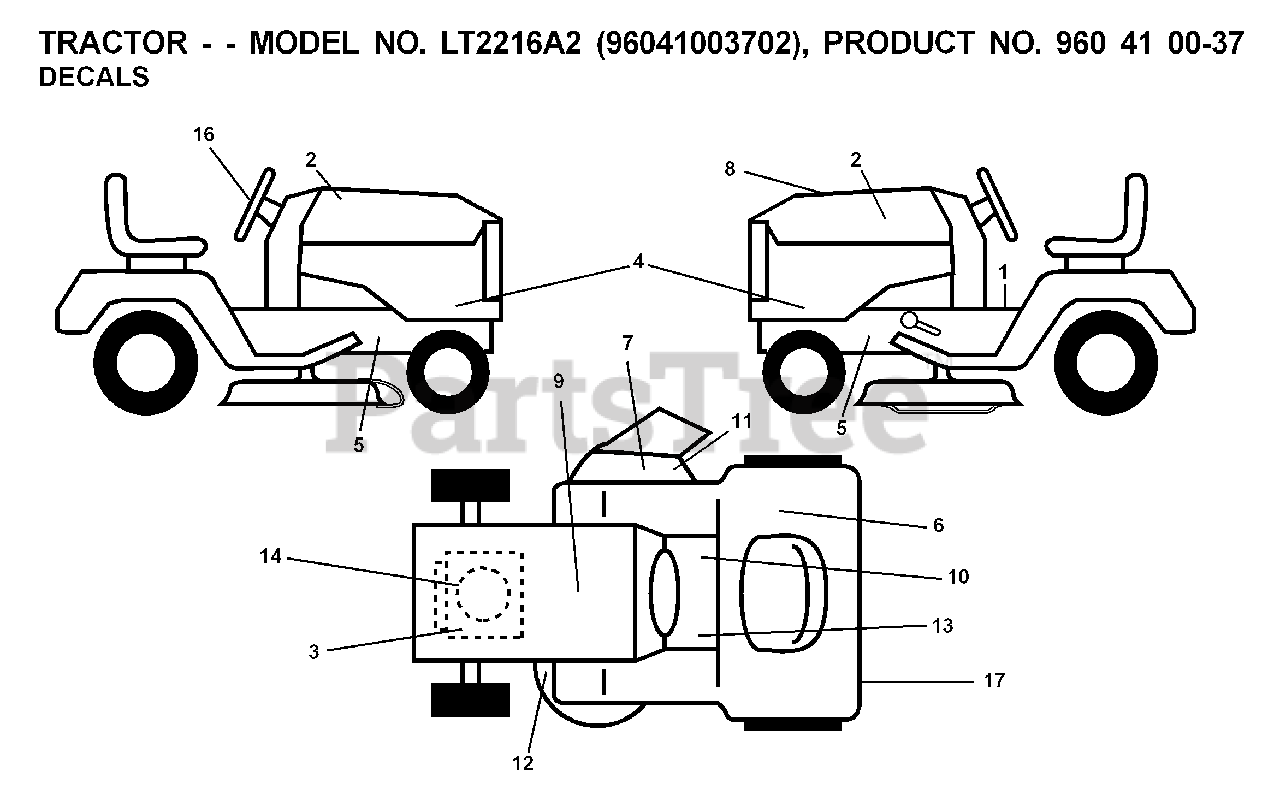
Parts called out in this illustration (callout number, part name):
7	DECAL.INTERNATIONL.CUTFINGER
9	DECAL BTRY SYMBOLS
10	DECAL PARK BRAKE
11	DECAL, DEFLECT WARNING
12	DECAL V BELT SCHEMATIC
